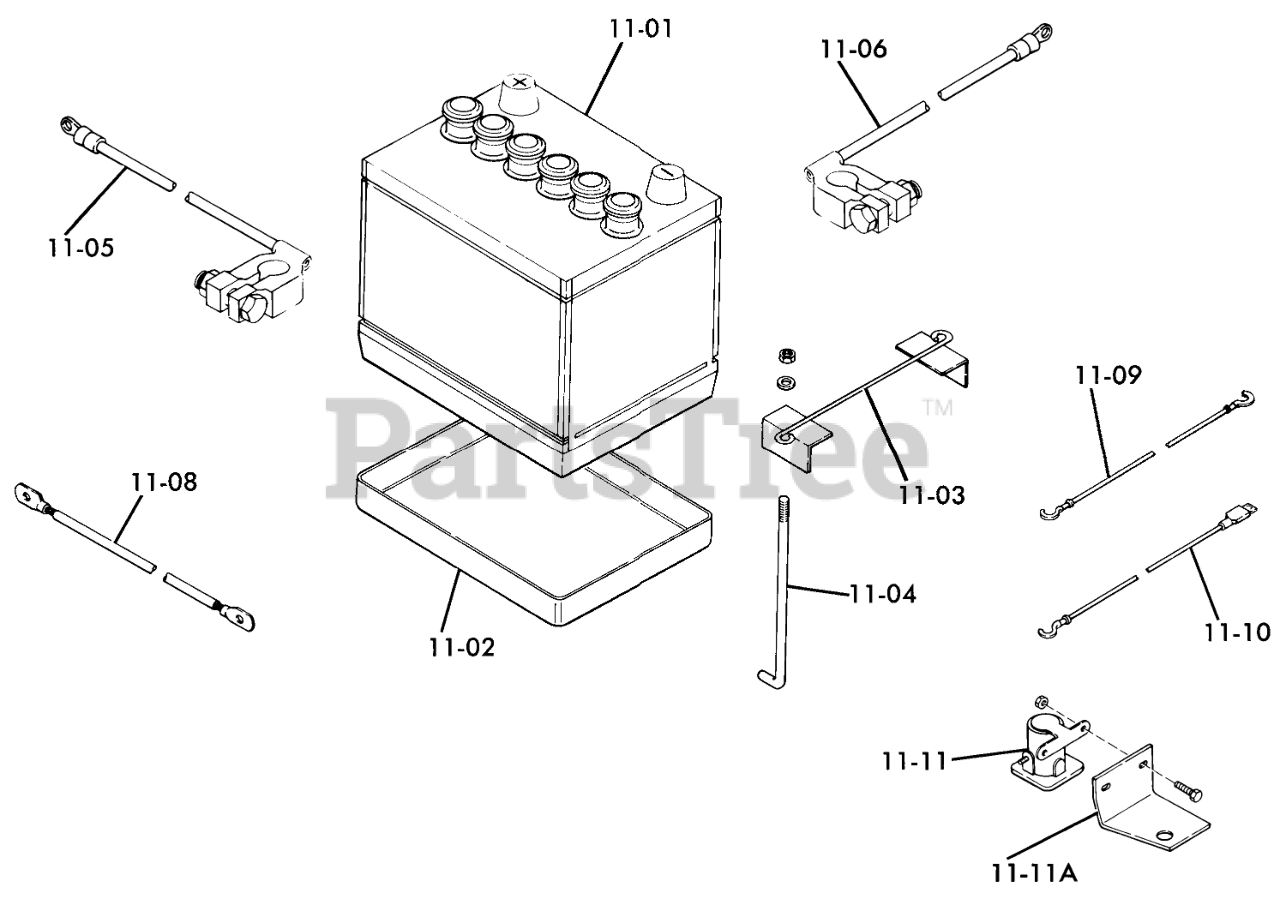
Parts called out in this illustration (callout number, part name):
11-01	Battery
11-02	Battery Box
11-03	Assy-Hold Down
11-04	Hook-Battery Retainer
11-05	ASSY-WIRE SOLENOID
11-06	ASSY-WIRE
11-08	Starter-Solenoid 20 1/2"
11-08	Cable
11-09	WIRE ASSY
11-10	Assy-Wire
11-11	Solenoid
11-11A	Bracket
11-12	SWITCH SAFETY
11-13	NUT-SPECIAL 9/16-18
11-15	Control Clip
11-16	Wire Assy
11-17	HEADLAMP
11-18	Grommet
11-19	BASE-TAIL LIGHT
11-20	Lens-Taillight
11-21	SWITCH CLUTCH
11-23	CONNECTOR 3 WIRE
11-24	SPEED CLIP
11-25	Grommet
11-26	ASSY FUSED CONNECTOR
11-27	SWITCH-LIGHTS
11-28	Wiring Harness
11-29	SWITCH-IGNITION
11-30	Key-EL
11-31	AMMETER W/CLAMP
11-32	Gauge-Oil Temp
11-33	Assy-Thermistor
11-34	Assy-Wre
11-35	REGULATOR-RECTIFIER
11-36	Clamp
11-36	Hour Meter
11-36A	Wire Assy
11-37	CLAMP MOUNTING
11-37	Gauge-Oil Pressure
11-37A	SENDER-OIL PRESSURE
11-38	SY WIRE HR METER G
11-38	LAMP-DASH
11-39	Assy-Wire Gauge
